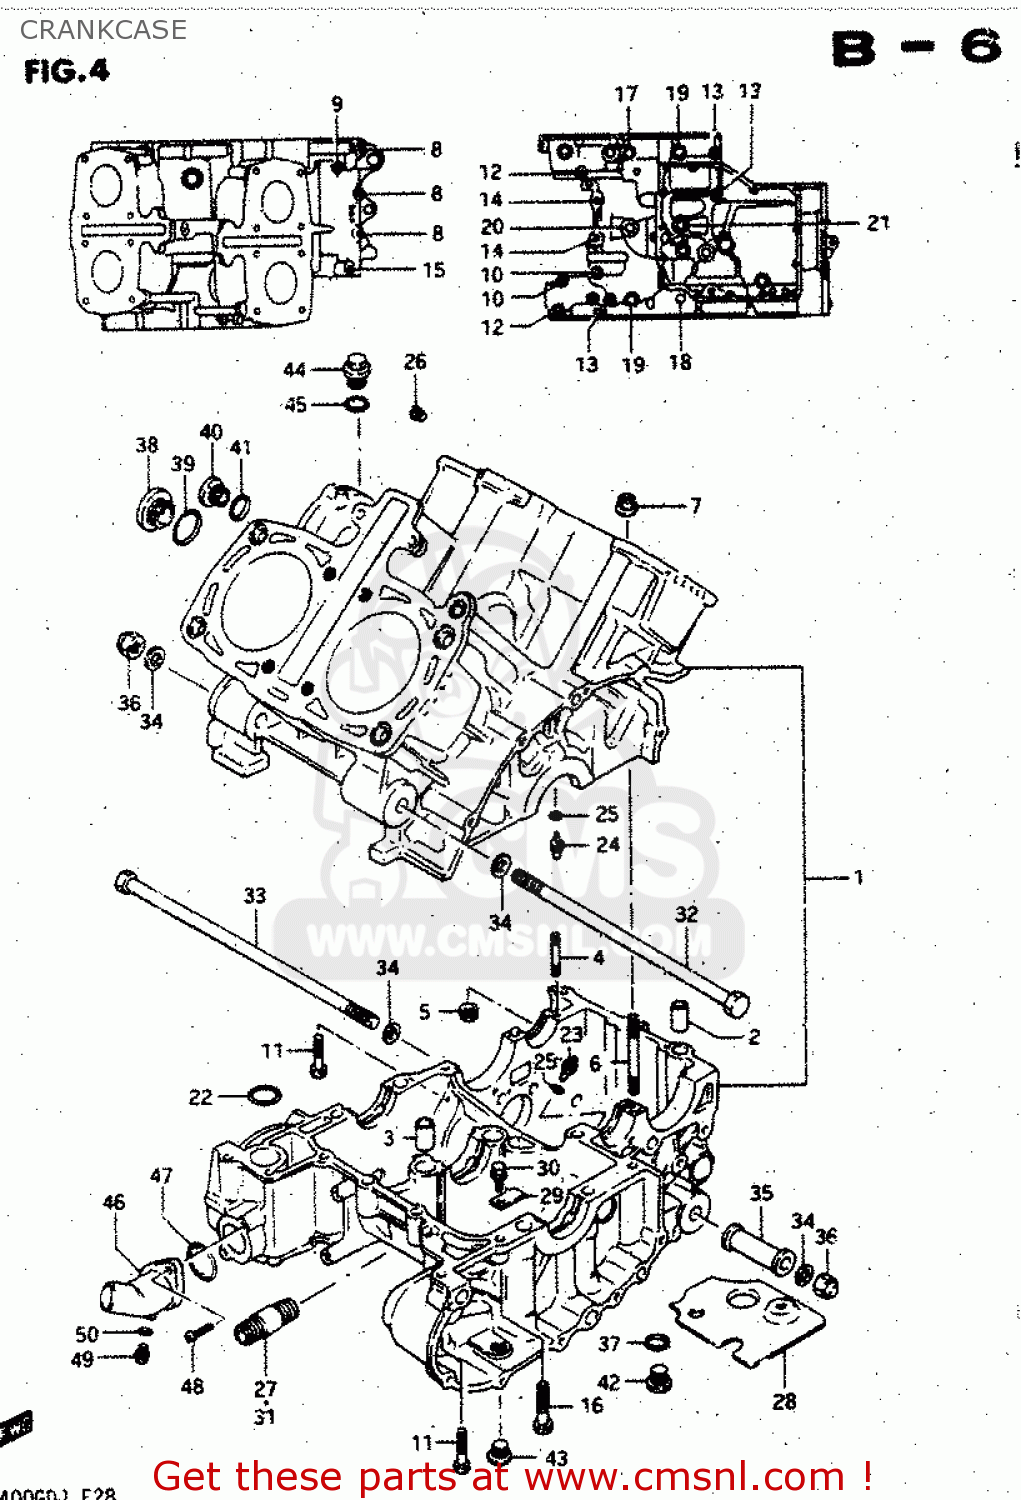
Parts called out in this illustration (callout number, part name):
1	CRANKCASE SET
2	PIN(10.4X13X22)
3	PIN
4	STUD 6X50
5	NUT
6	STUD BOLT
7	NUT 8MM
8	BOLT 6X35
9	BOLT
10	BOLT (6X90)
11	BOLT
12	BOLT(6X100)
13	BOLT(8X125)
14	BOLT
15	BOLT 8X60
16	BOLT 8X35
17	BOLT 10X145
18	BOLT(10X150)
19	BOLT(10X125)
20	BOLT
21	BOLT
22	O-RING (D:3 ID:27)
23	JET,OIL GALLERY
24	JET,OIL GALLERY(16)
25	O RING(D:1.2,ID:4)
26	PLUG
27	UNION,OIL STAND
28	PLATE,OIL SEPARATOR
29	MAGNET, DUST CATCH
30	BOLT
31	UNION,OIL STAND
32	BOLT
33	BOLT
34	WASHER 10MM
35	SPACER,ENG MTG(L:55)
36	NUT
37	GASKET(16X22X2) (NAS)
38	PLUG
39	O-RING
40	PLUG
41	O RING(D:3.1,ID:16.8)
42	PLUG
43	PLUG
44	PLUG
45	O RING(D:3.1,ID:16.8)
46	CONNECTOR,WATER INLET
47	O RING(D:2.4,ID:31.7)
48	SCREW
49	BOLT,DRAIN
50	GASKET 8.2X14X1 (NAS)
